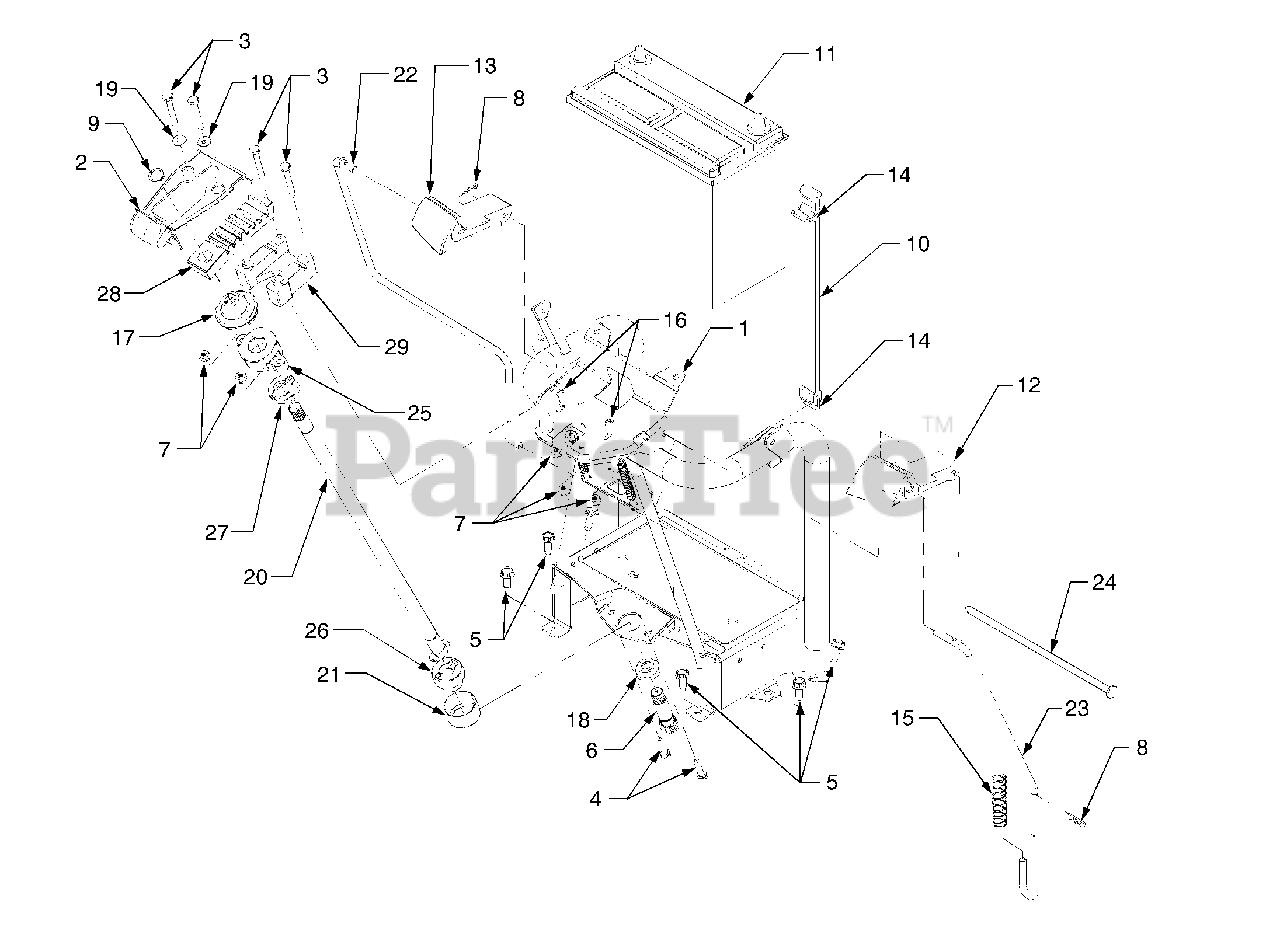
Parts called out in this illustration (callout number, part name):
1	Pedestal Assembly
2	Handle, Tilt
3	Screw, Hex Cap 1/4-20 x 1.75 GR5
4	Screw, Hex Cap 1/4-20 x 1.0 GR5
5	Screw, Hex Wash. Hd. Tapp 5/16-18 x .75
6	Shaft, Lower Steering
7	Nut, Hex Insert Lock, 1/4-20
8	Pin, Internal Cotter
9	Ring, Retaining, .56 Dia Shaft
10	Strap, Battery
11	Battery
12	Lever, Park Brake
13	Lever, Cruise
14	Hook, Wire Rectangular
15	Spring, Compression, .676 x 2.5
16	Spring, Extension
17	Boot, Tilt Wheel Coupling
18	Boot, Shaft Cover
19	Washer, Flat, .271 x .63 x .065
20	Shaft, Upper Steering
21	Bearing, Sleeve, 1.44 x 1.5 x .812
22	Rod, Cruise Control
23	Rod, Parking Brake
24	Rod, Cruise/Brake Pivot
25	Housing, Tilt Wheel Coupling
26	Coupling Half, Bottom
27	Coupling Half, Top
28	Index, Tilt Steering
29	Block, Tilt Steering
